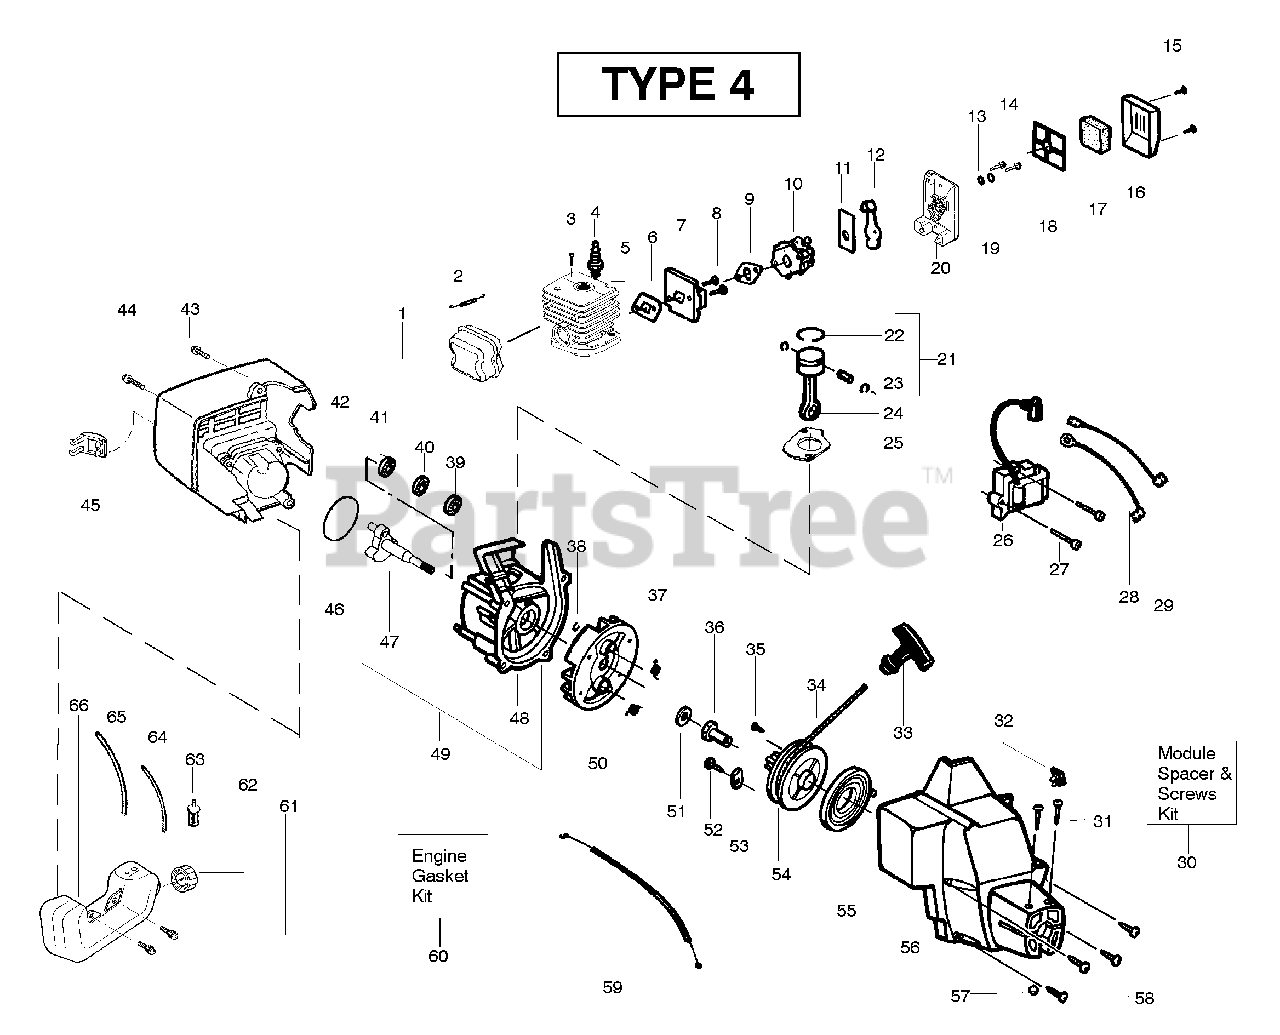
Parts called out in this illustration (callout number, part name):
1	Kit - Muffler
2	Muffler Spring
3	Screw-Cylinder
4	Spark Plug (RCJ 6Y)
5	Kit - Cylinder
6	Gasket-Cyl/Carb.(kit)
7	Adaptor-carb.
9	Gasket-Carb.(kit)
10	Kit-Carb. (WT-631)
11	Plate-Choke Mounting
12	Lever-Choke
16	Cover-Air Box
17	Foam-Air Filter
18	Plate-Air Filter Support
19	Spacer-Choke
21	Kit - Piston
22	Piston Ring
23	Retainer-Piston Pin
24	Assy-Connecting Rod
25	Gasket-Cylinder(kit)
26	Ignition Module
28	Assy-Ground Wire
29	Assy-Leadwire
30	Kit-Module Spacer & Screws
32	Kit-Switch
33	Handle-Starter
34	Kit - Rope
36	Coupling-Drive
37	Spring-Starter Dog
38	Retain. Ring-C'shaft
39	Bearing-Outer
40	Kit-C'case Seal
41	Bearing-Inner
44	Screw
45	Guard-Muffler
46	O-Ring-C'case(kit)
47	Assy-Crankshaft
48	Assy-Crankcase
49	Assy-C'case & C'shaft
50	Assy-Flywheel
51	Washer-Flat
53	Retainer-Pulley
54	Kit-Starter Pulley
55	Spring-Starter
56	Assy-Fan Housing
58	Screw
59	Kit-Throttle Cable
60	Kit-Engine Gasket
61	Retainer-Fuel Tank
62	Assy-Fuel Cap
63	Assy-Fuel Pickup
64	Kit-Fuel Line
65	Kit-Fuel Line
66	Assy-Fuel Tank
